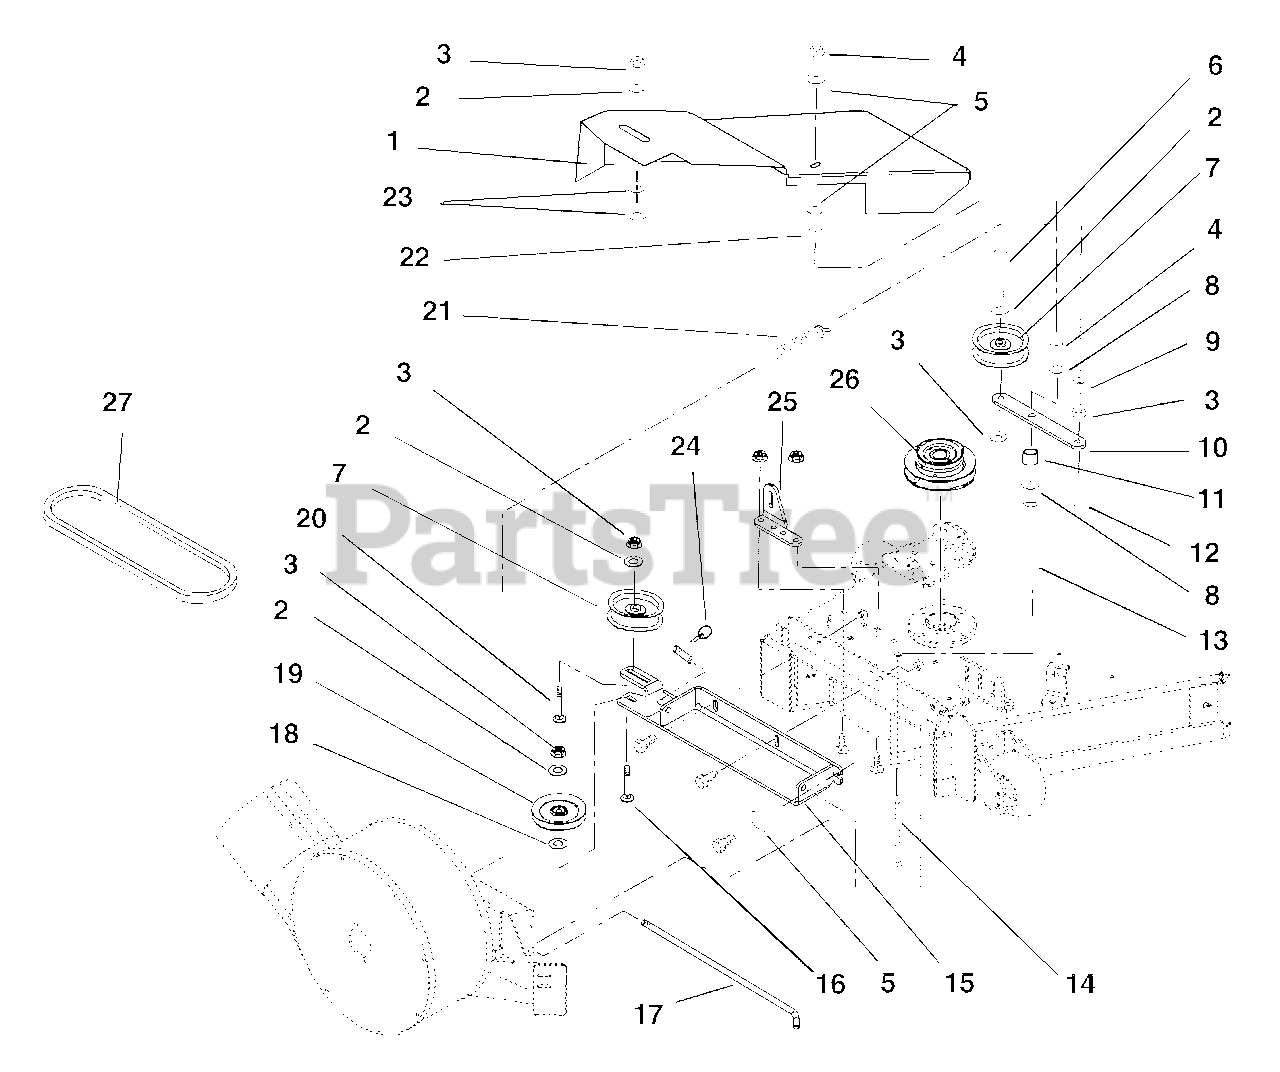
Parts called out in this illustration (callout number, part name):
1	Weldment, Belt Guard
2	Washer-Flat-Steel .438 x 1.00 x .083
3	Nut-Locking-Top-Flange .38-16
4	Nut-Locking-Top-Flange .31-18
5	Washer-Flat-Steel .38 x .875 x .083
6	Bolt-Hex .38-16 x 1.75 Grade 5
7	Idler Flanged 3.50
8	Washer-Flat-Steel .344 x 1.125 x .13
9	Nut-Locking-Center .38-16
10	Arm, Idler
11	Spacer .380 x .503 x .281
12	Bolt-Hex .38-16 x 1.25 Grade 5
13	Spacer .391 x .625 x 1
14	Bolt .312-18 x 4.00
15	Weldment, Pivot Mount 44,48,52
16	Bolt-Round Head Square Neck .38-16 x 1.75 Grade 5
17	Rod, Pivot
18	Washer-Flat-Steel .406 x 1.00 x .188
19	Idler-V 4.00 x .38
20	Bolt-Round Head Square Neck .38-16 x 2.50 Grade 5
21	Spring-Tension .080 x .687 x 5.16
22	Nut-Locking-Center .31-18
23	Washer-Flat-Steel .406 x 1.375 x .135
24	Pin-Klik 1.00 x .188 x 1.25
25	Bracket, 52-Inch Deck Mounting
26	Pulley, Double V 3.50/5.25 Diameter
27	V-Belt 52-Inch Mower Deck
